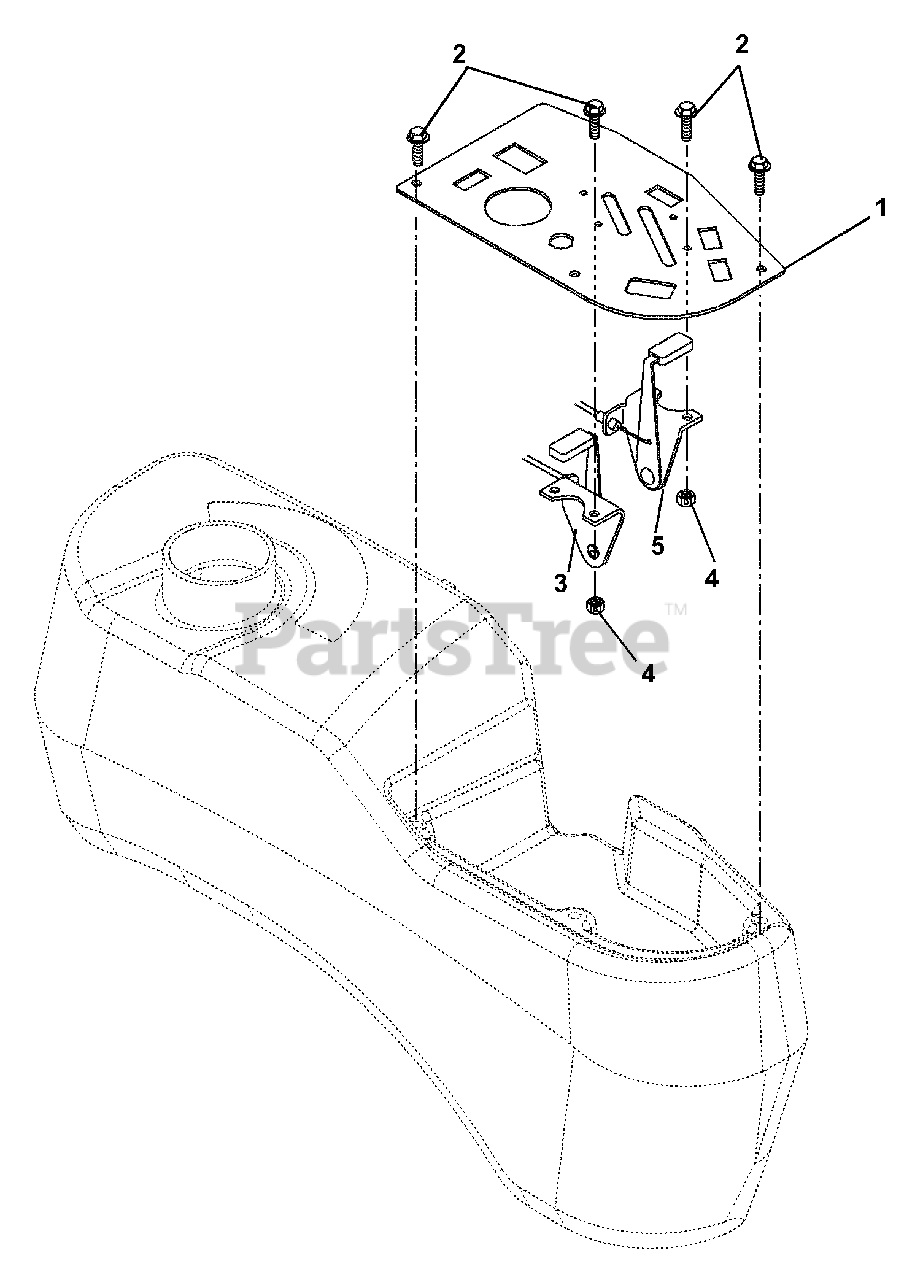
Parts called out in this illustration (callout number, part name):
1	Panel-Control
2	Screw-Machine 10-24 x .50 Hex Washer Head (060, 061, 075, 076, 318, 319)
2	Screw-Machine 10-24 x .50 Hex Washer Head (058, 059, 073, 074)
3	Throttle, Control (060, 061, 075, 076, 318, 319)
3	Throttle, Control (058, 059, 073, 074)
4	Nut-Locking-Nylon 10-24 With Insert (060, 061, 075, 076, 318, 319)
4	Nut-Locking-Nylon 10-24 With Insert (058, 059, 073, 074)
5	Choke Control (058, 059, 073, 074)
